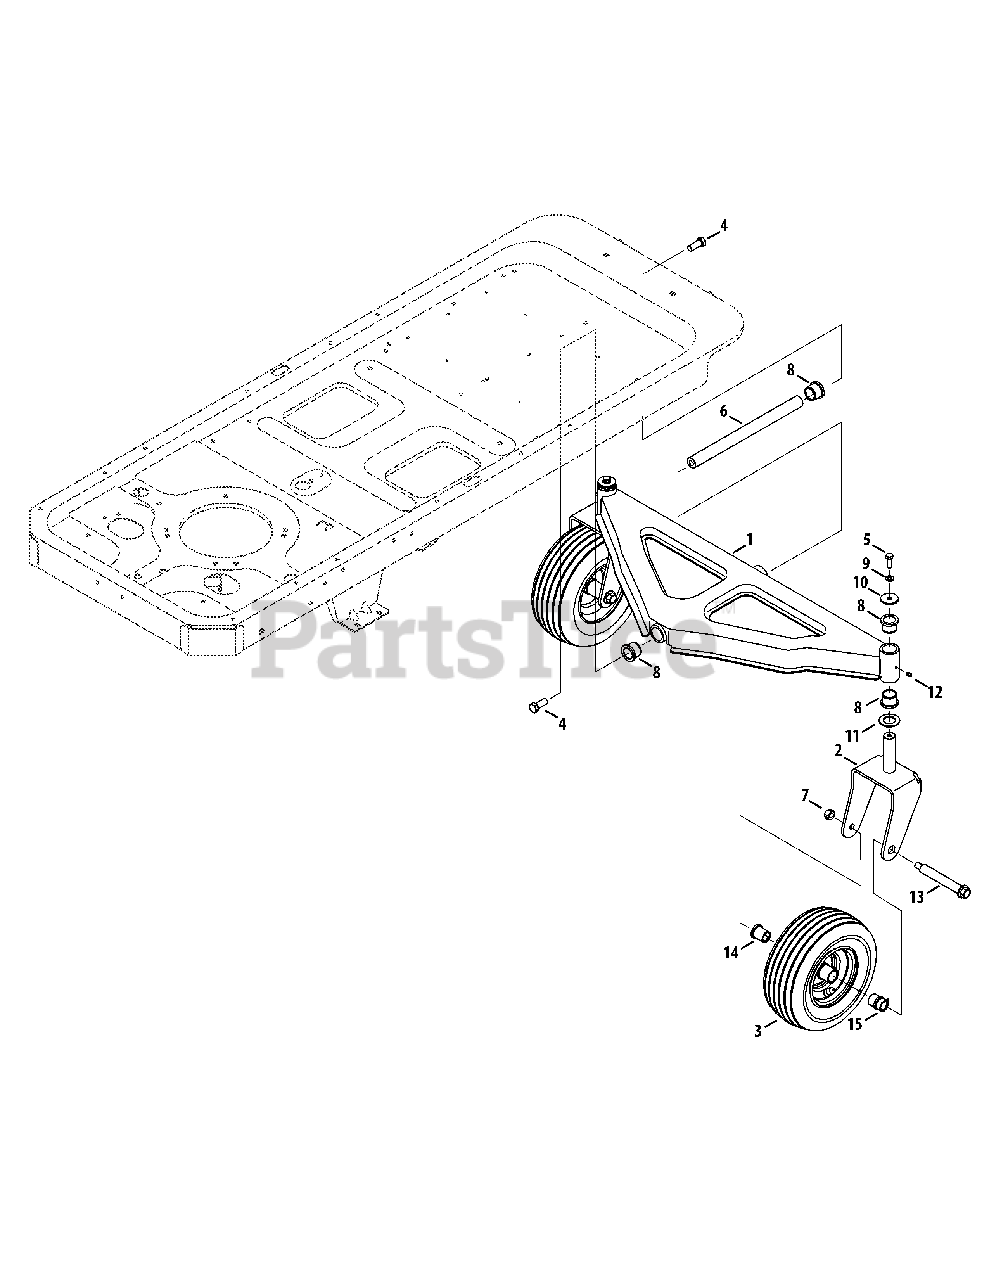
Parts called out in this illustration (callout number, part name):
1	Front Pivot Axle
2	Castor Wheel Bracket
3	Wheel Assembly, 11.0 x 4.0 x 5.0
4	Hex Lock Screw, 1/2-13 x 1.25
5	Hex Cap Screw, 3/8-16 x 1.0
6	Axle Shaft
7	Hex Lock Nut, 1/2-13
8	Flange Bearing, 1.0 x 1.246
9	Lock Washer, 3/8
10	Flat Washer, .39 x 1.5 x .134
11	Flat Washer, 1.0 x 1.75 x .107
12	Lube Fitting, 3/16
13	Shoulder Screw, 7/16-14 x .75 x 4.75
14	Flange Bearing, .76 x 1.0 x 1.2
15	Flange Bearing, .76 ID w/Lube Ftg.
